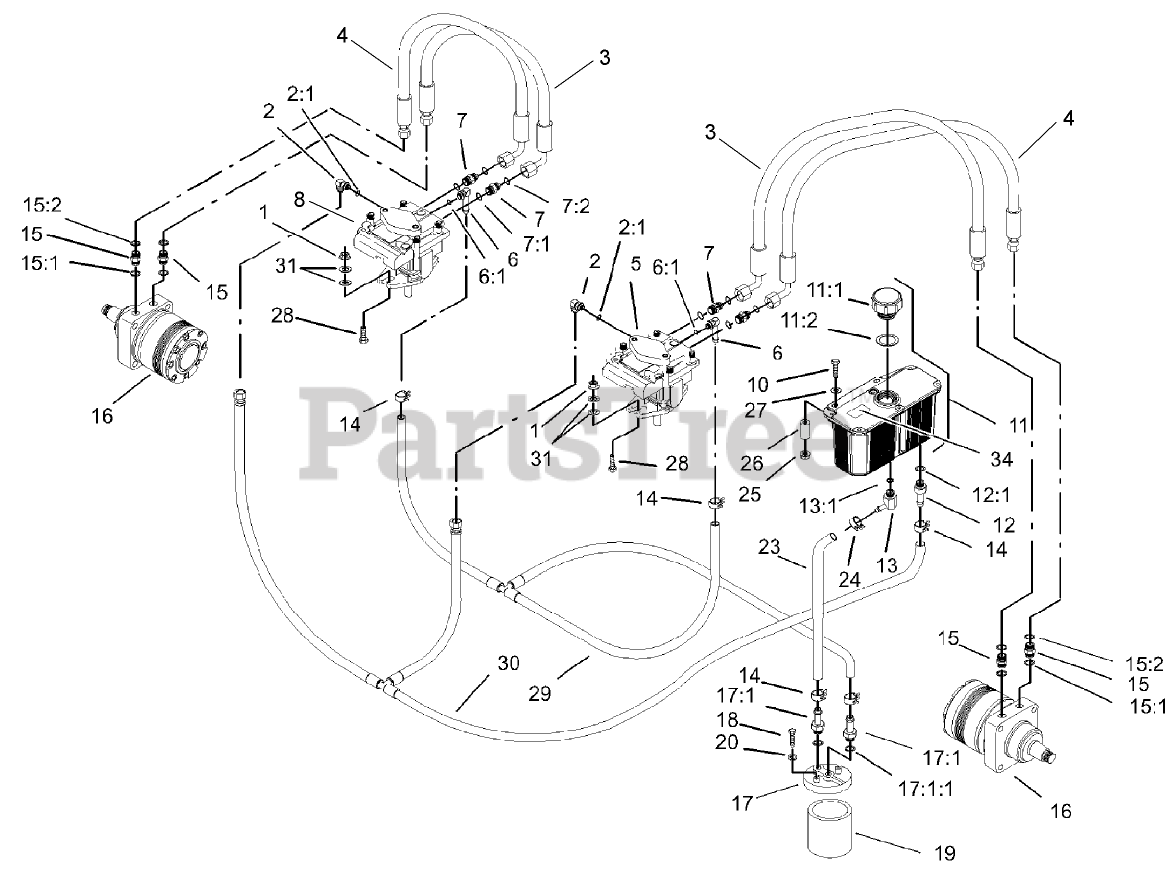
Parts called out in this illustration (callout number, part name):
1	NUT-HHF, WHIZ
2	FITTING-ELBOW, 90 DEG
2:1	O-Ring
3	HOSE-PRESSURE, HIGH
4	HOSE-PRESSURE, HIGH
5	PUMP-HYD
6	ELBOW-90 DEG
6:1	O-RING
7	FITTING-STRAIGHT
7:1	O-RING
7:2	O-Ring
8	HYDRAULIC PUMP ASM
10	SCREW-HH
11	Reservoir-HYD
11:1	CAP-RESERVOIR, HYD
11:2	GASKET-CAP
12	Adapter-Straight
12:1	O-RING
13	FITTING-BARBED, 45 DEG
13:1	O-RING
14	Clamp-Hose
15	Fitting-Straight
15:1	O-RING
15:2	O-Ring
16	HYD MOTOR ASM
17	Filter Head ASM
17:1	ADAPTER-STRAIGHT
17:1:1	O-RING
18	SCREW-HH
19	FILTER-OIL, HYD
20	WASHER-LOCK
23	Hose-Charge
24	Clamp-Hose
25	NUT-HF
26	Spacer
27	WASHER-FLAT
28	SCREW-HH
29	CHARGE HOSE ASM
30	CASE DRAIN HOSE ASM
31	WASHER-FLAT
34	DECAL-TANK, HYD
